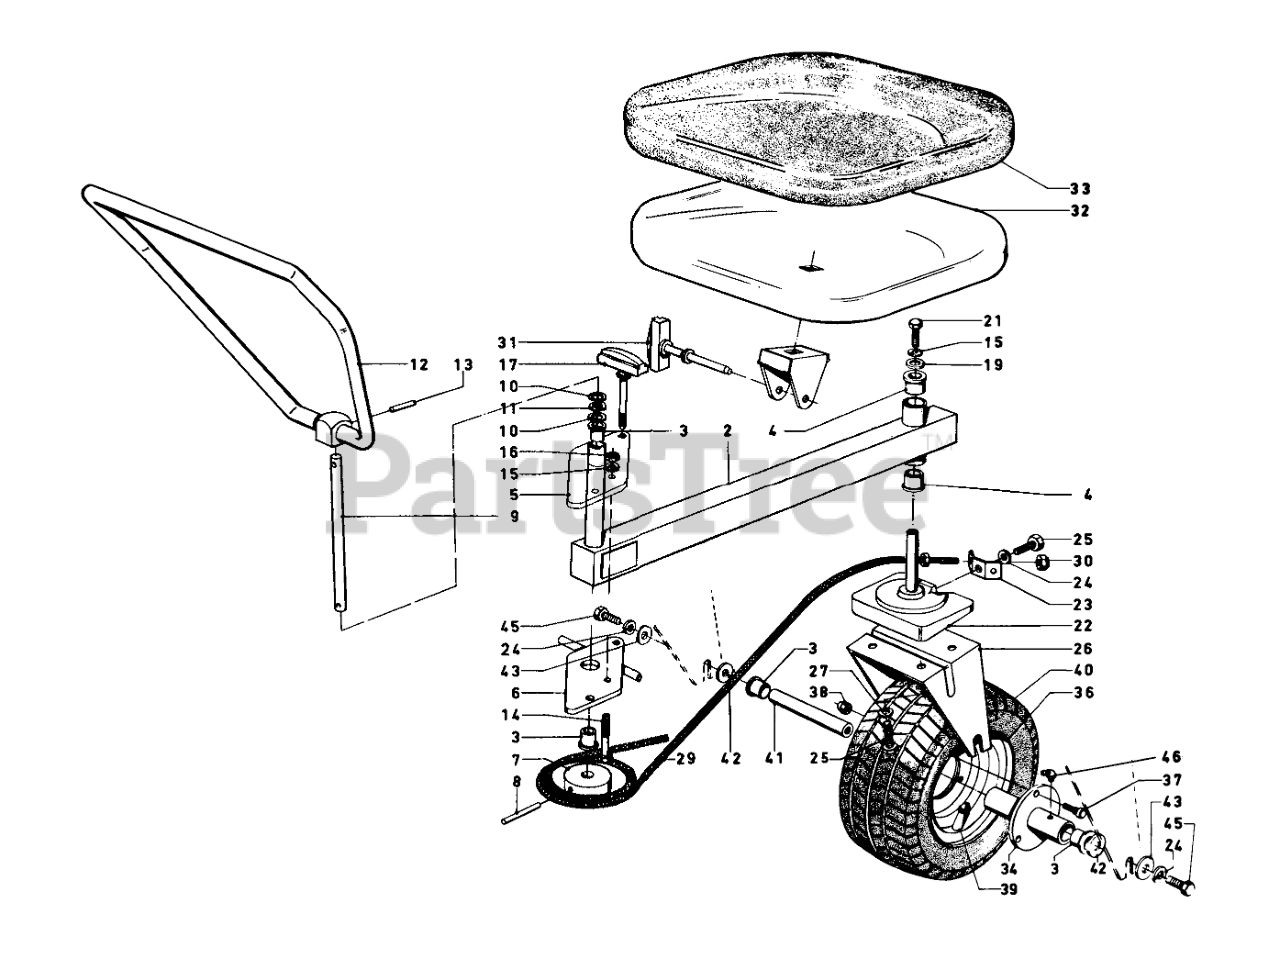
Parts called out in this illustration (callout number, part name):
3	3/4IDX1LG FLANGE BSHG
4	FLANGE BUSHING
7	FRT STRG PULLEY *RO
9	Shaft, Steering
10	Washer, Thrust
11	3/4 SPRING WASHER
12	STEERING HANDLE ASM
13	PIN-ROLL, SLOTTED
14	Capscrew
15	WASHER-LOCK
16	NUT-HEX
17	STUD HANDLE ASM
21	SCREW-HH
22	PVT CSTR/SFT WA*RO
23	CABLE BRACKET *R
24	WASHER-LOCK
25	SCREW-HH
27	WASHER-LOCK
29	STRG SWAGED CABLE ASM
30	NUT-LOCK
37	DRIVE STUD
38	LUG NUT
42	THRUST WASHER
43	WASHER-FLAT
45	SCREW-HH
46	FITTING-LUBE, 45 DEG
